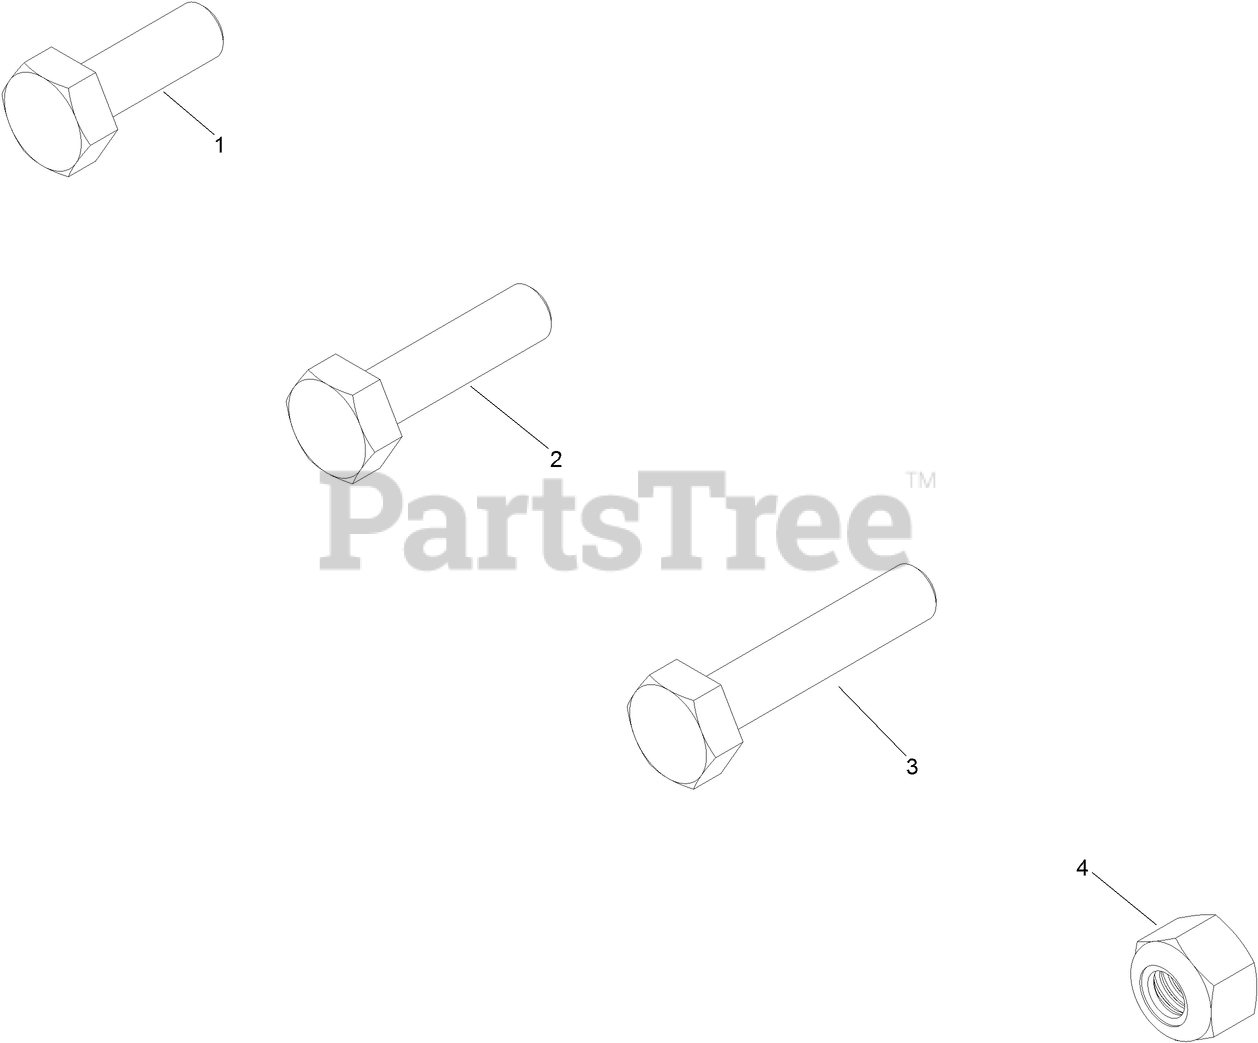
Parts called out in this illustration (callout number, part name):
1	SCREW-HH
2	SCREW-HH
3	SCREW-HH
4	NUT-LOCK
